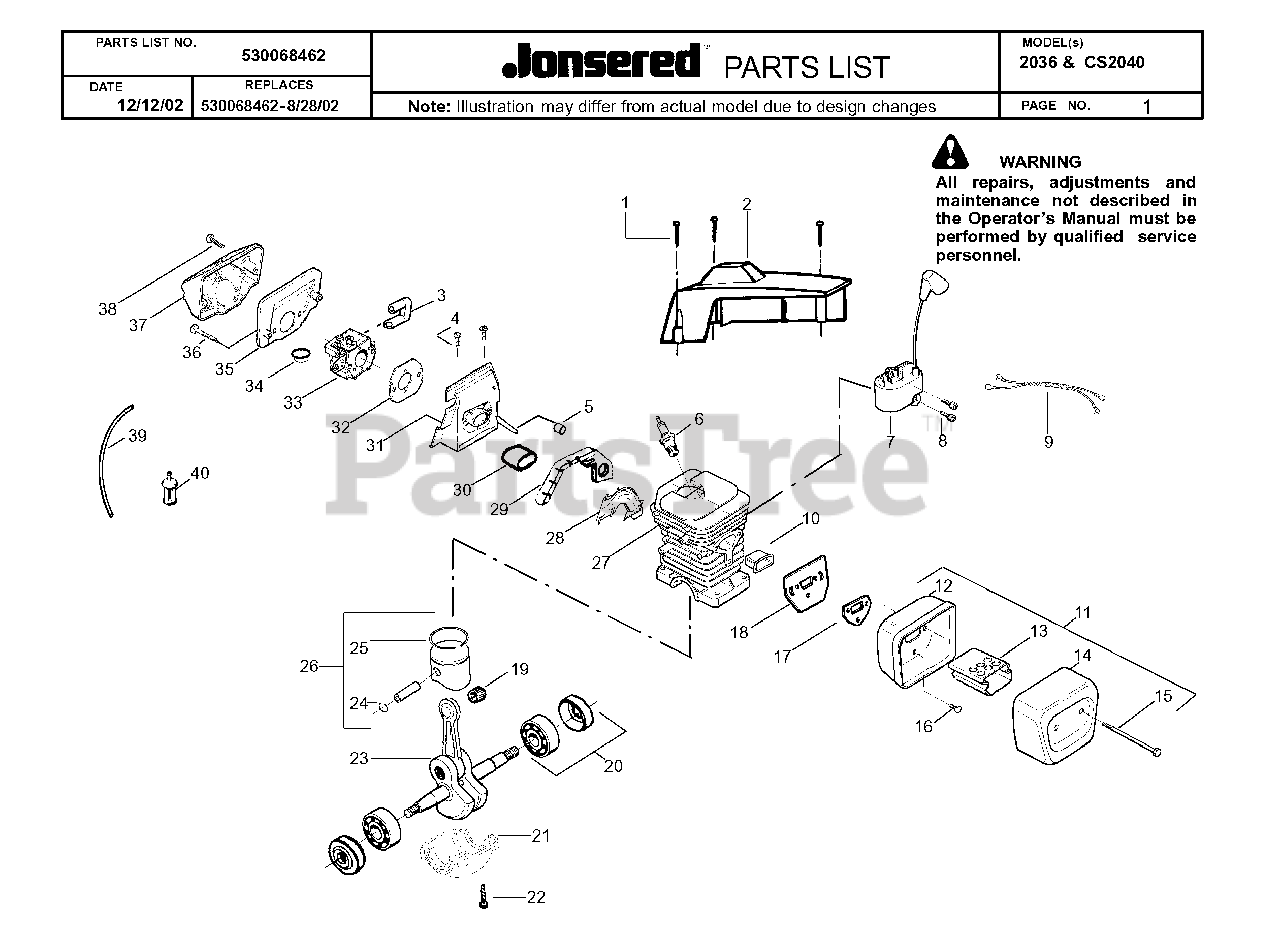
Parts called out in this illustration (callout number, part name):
3	CARB GROMMET
5	IMPULSE PIPE
6	SPARK PLUG (RCJ-7Y)
7	%IGNITION MODULE
8	SCREW,IGN MOD 36/41
9	SHORTING LEAD
10	HEAT INSULATOR
13	FLAME PROTECTION
16	BOLT-MUFFLER(SUPPORT)
18	MUFFLER PLATE
19	PISTON PIN BEARING
20	BEARING & SEAL ASSEMBLY
21	CAP-CRANKSHAFT
22	B0LT, C/SHAFT 36/41
23	B0LT, C/SHAFT 36/41
24	C-CLIP,PSTN PIN 36/41
25	C-CLIP,PSTN PIN 36/41
26	PISTON RING HV41
27	KIT-PISTON
28	INTAKE HORN
29	TURBO CLEAN SEAL
30	INTAKE PIPE
31	CARB ADAPTOR
32	GSKT,CARB 36/41
33	CARBURETOR/EPA
34	CRANKCASE ISOLATOR
35	HOLDER
37	AIR FILTER
40	FUEL PICK-UP ASSY
530029805	PISTON RING 36
530029982	PISTON RING HV41
530031135	SCRENCH
530069454	KIT-PISTON
530069940	CYLINDER ASSY/136
530069941	CYLINDER ASSY/141
530069944	PISTON KIT/136
